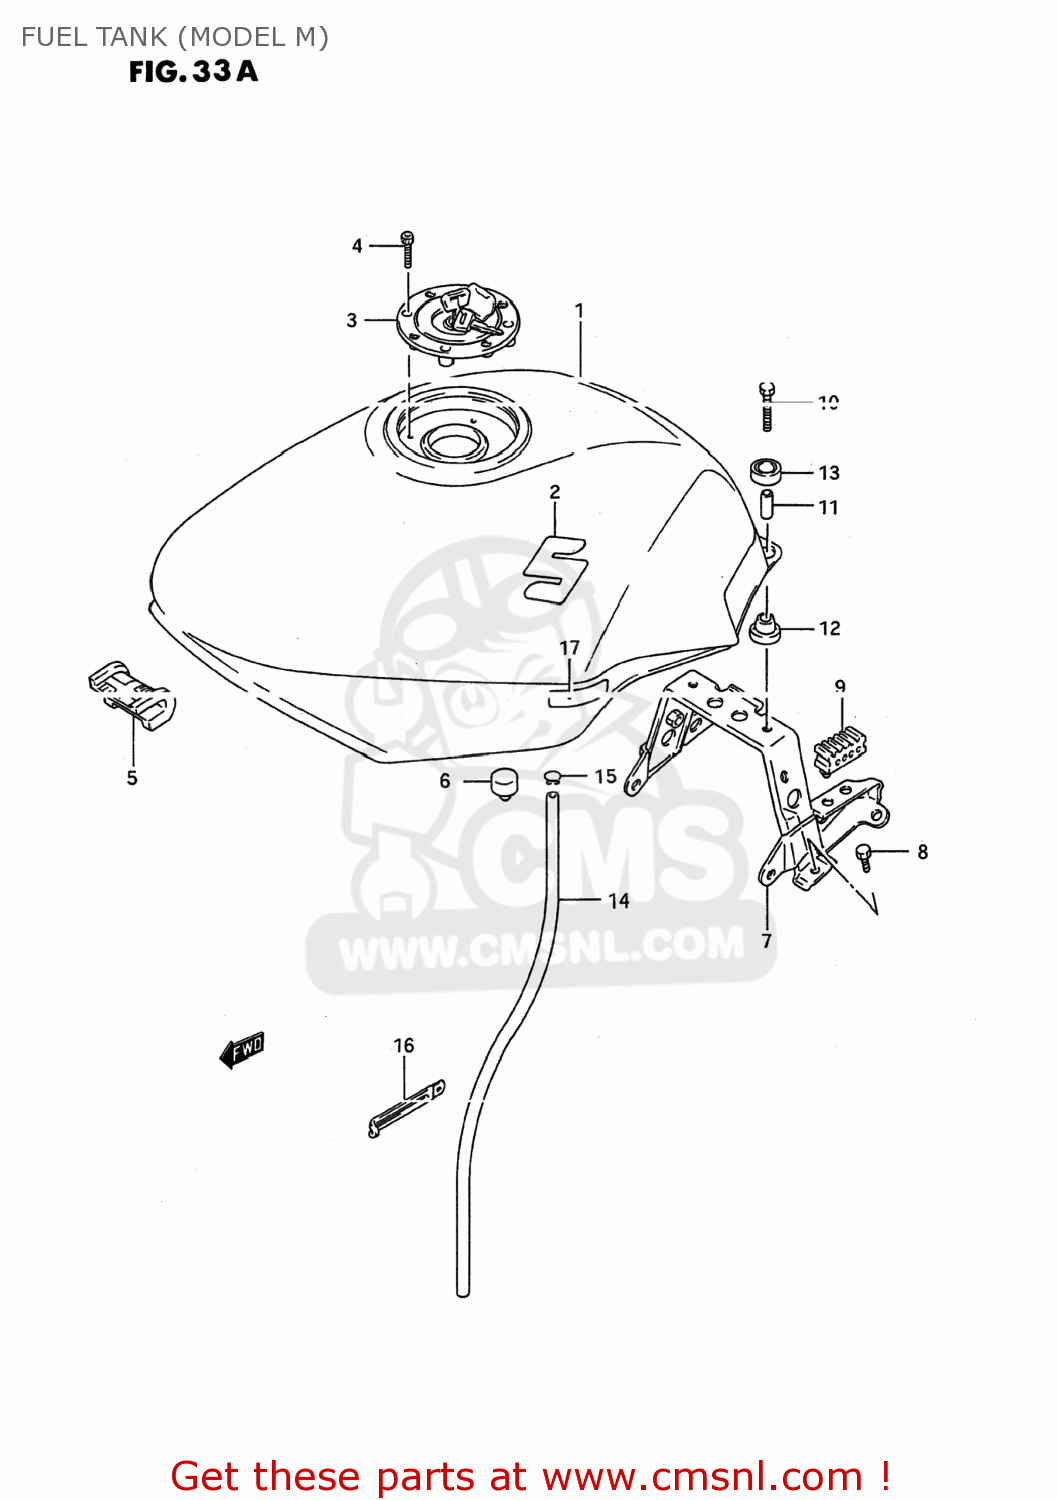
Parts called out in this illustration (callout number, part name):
1	TANK ASSEMBLY,FUEL
2	EMBLEM,FUEL TANK
3	CAP SET,FUEL TANK
4	BOLT(5X20)
5	CUSHION,FUEL TANK FR
6	CUSHION
7	BRACKET,FUEL TANK RR
8	SCREW
9	CUSHION,SEAT(40X20X15)
10	BOLT
11	SPACER
12	CUSHION
13	CUSHION
14	HOSE,FUEL TANK WATER DRAIN
15	CLIP
16	CLAMP(L:120 T:1.0)
17	PROTECTOR,FUEL TANK,LEFT
